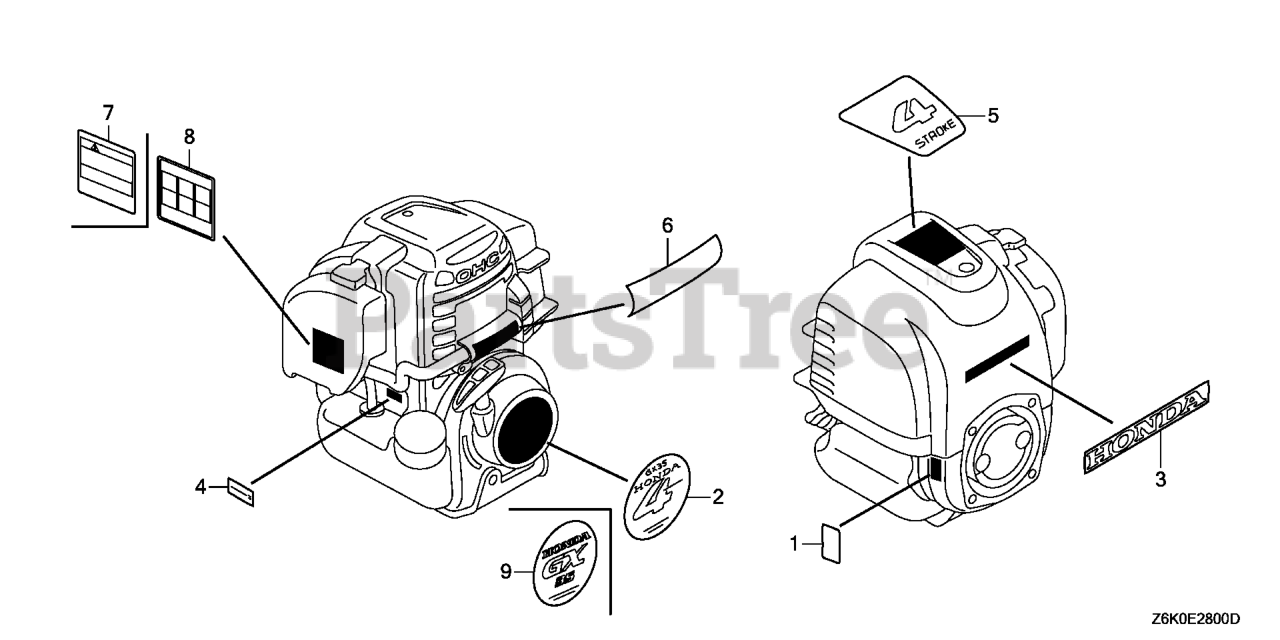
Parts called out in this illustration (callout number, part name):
1	LABEL, WARNING (NOT CERTIFIED FOR SALE)
3	MARK, HONDA
4	MARK, TYPE (TMS3)
5	MARK (4-STROKE)
7	MARK, OPER CAUTION
9	MARK, EMBLEM
